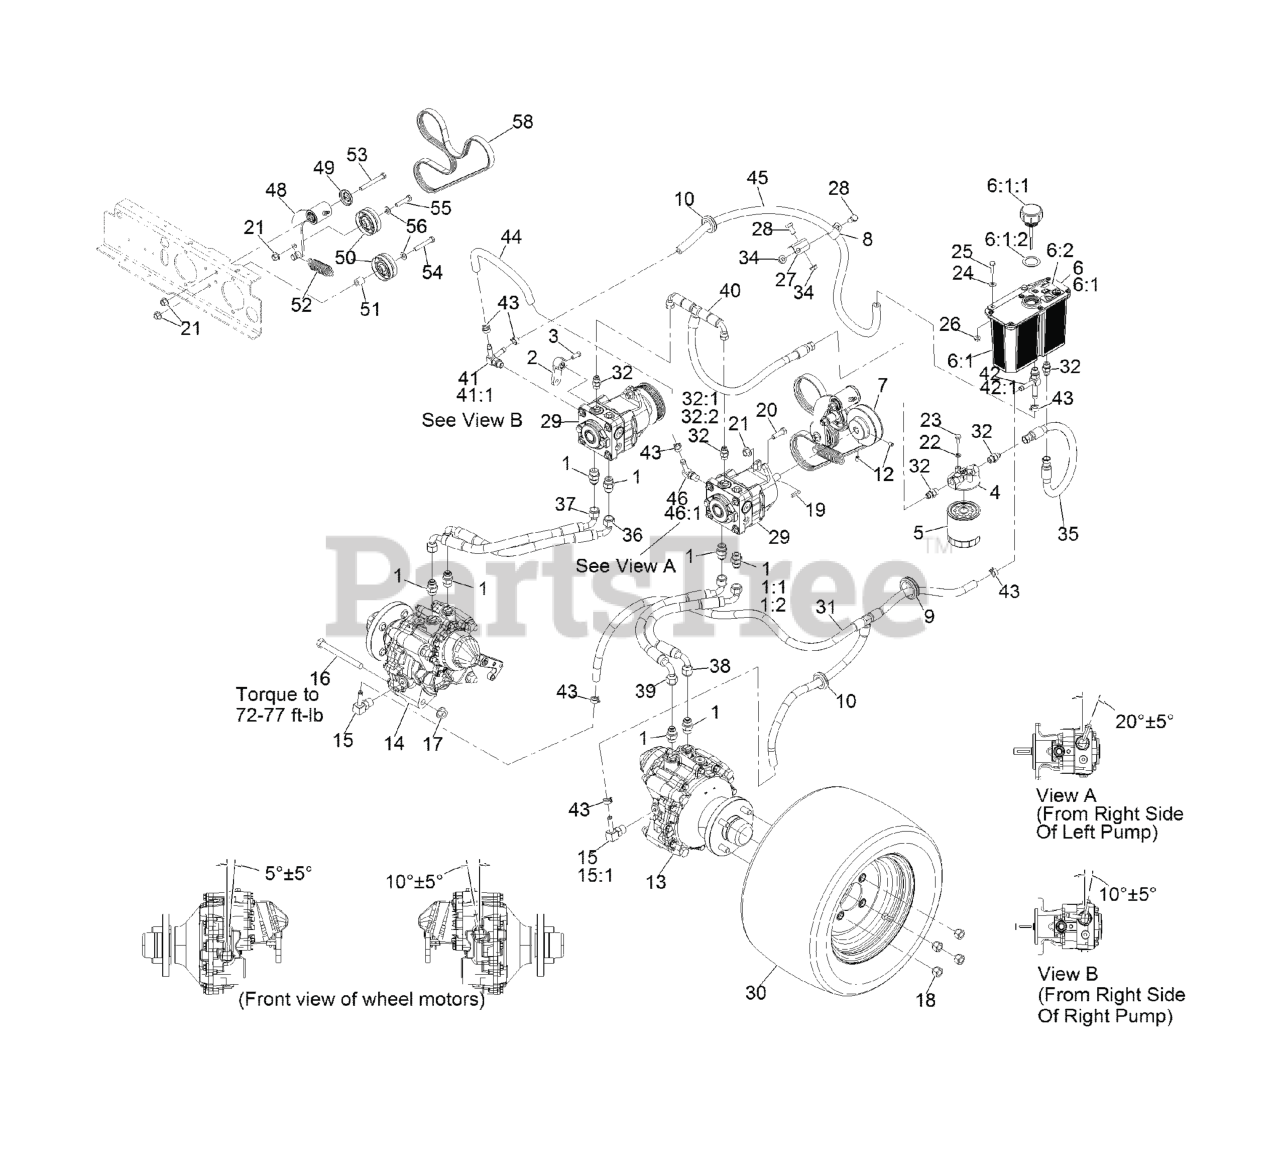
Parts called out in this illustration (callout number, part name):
1	FITTING-STRAIGHT
2	ARM-CONTROL, PUMP
3	SCREW-SET, SQH
4	HEAD-FILTER
5	FILTER-25 MICRON, BI-DIRECTIONAL
6	RESERVOIR ASM
6:1	Reservoir-HYD
6:1:1	RESERVOIR CAP ASM
6:1:2	GASKET-CAP
6:2	DECAL-WARNING
8	CLIP-LOOM
9	GROMMET
10	GROMMET
12	SCREW-SET
13	MOTOR-HYD, LH
14	MOTOR-HYD, RH
15	FITTING-90
15:1	O-RING
16	SCREW-HH
17	NUT-HHF
18	NUT-LUG
20	SCREW-HH
21	NUT-FLANGE
22	WASHER-LOCK
23	SCREW-HH
24	WASHER-FLAT
25	SCREW-HH
27	BRACKET-CLAMP
28	SCREW-HH
29	12CC HYDRO PUMP ASM
30	TIRE AND WHEEL ASM
31	HYDRAULIC HOSE ASM
32	FITTING-STRAIGHT
32:1	BOSS O-RING
34	NUT-HHF, WHIZ
35	HYDRAULIC HOSE ASM
36	HYDRAULIC HOSE ASM
37	HYDRAULIC HOSE ASM
38	HYDRAULIC HOSE ASM
39	HYDRAULIC HOSE ASM
40	HYDRAULIC HOSE ASM
41	ADAPTER-TEE
41:1	O-RING
42	ADAPTER-RUN, TEE
42:1	O-RING
43	CLAMP-HOSE
44	HOSE-HYD
45	HOSE-HYD
46	FITTING-ELBOW, 90
46:1	O-RING
48	IDLER ASM
49	GUARD-TOP
51	SPACER-MOUNTING, STEERING
52	SPRING-IDLER
53	SCREW-HH
54	SCREW-HH
55	SCREW-HH
56	WASHER-FLAT
